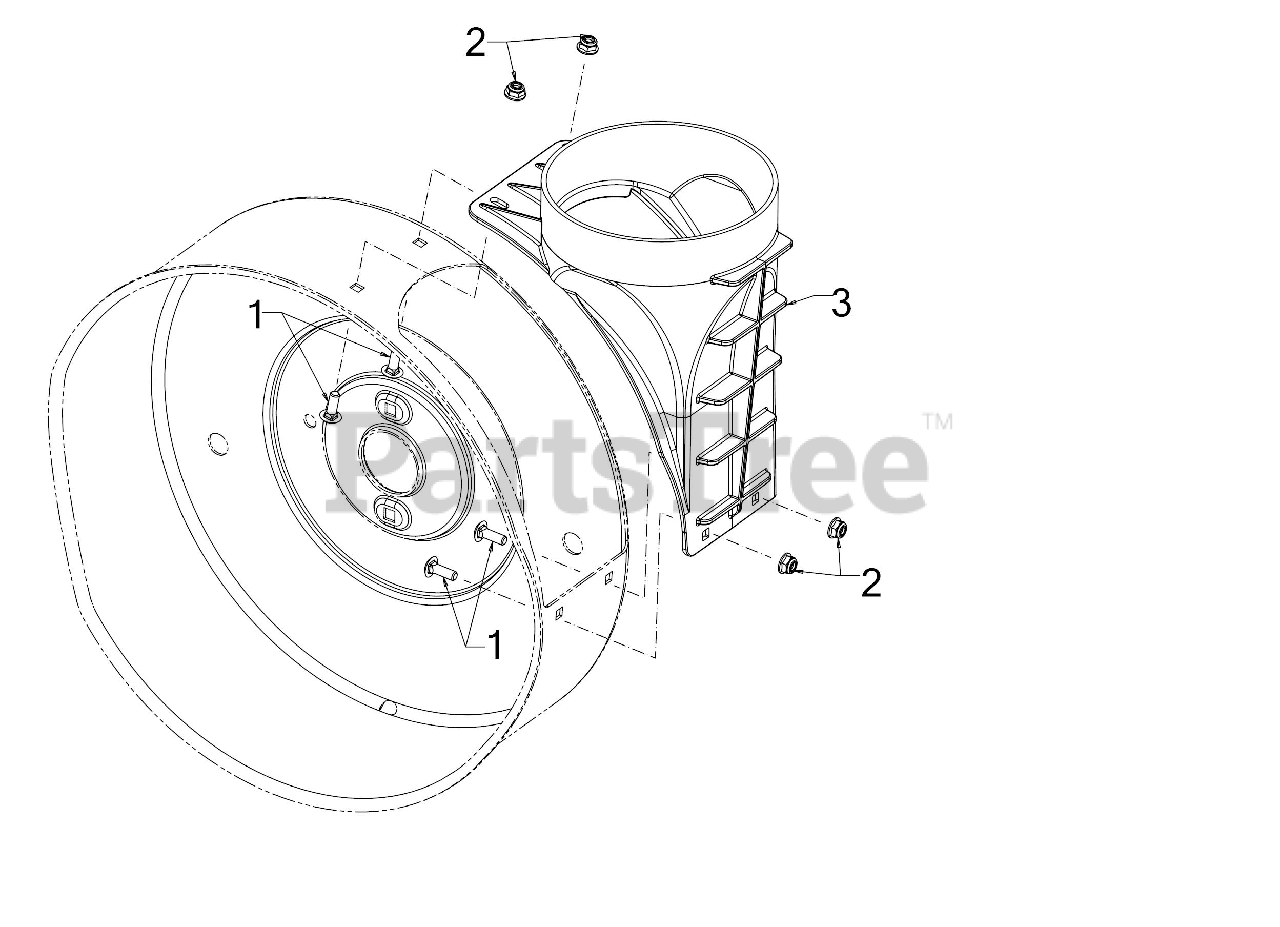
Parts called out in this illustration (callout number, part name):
1	SCREW 1/4-20 x .75 GR5
2	FLANGE LOCK NUT
3	6" CHUTE ADAPTER
